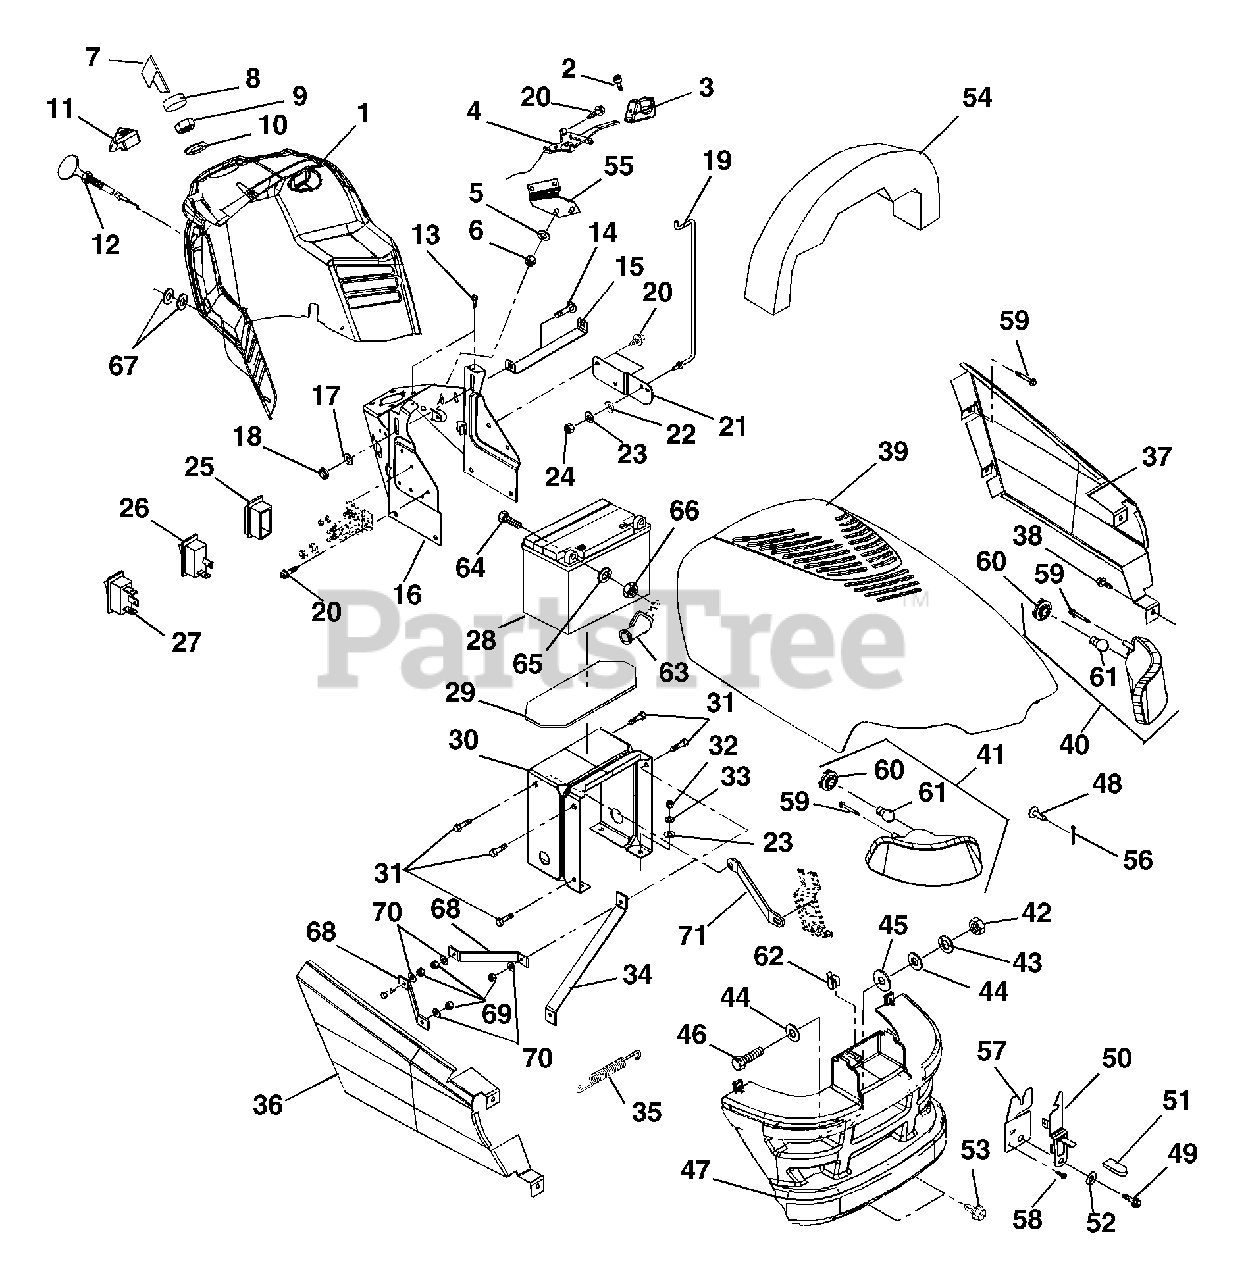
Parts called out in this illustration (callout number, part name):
1	DASH-VENTED
2	SCR-SET 10-24X.38 UNC-3A
3	KNOB, THROTTLE
4	THROTTLE CONTROL- TEC/B&S
5	WSHR-FL-STL .323X.625X.062 YWZ
6	@NUT-LK-CTR .25-20 YWZC
7	IGNITION SWITCH KEY
8	CAP - IGNITION SWITCH
9	NUT- PANEL .562-24 GRECO
10	WSHR-LK-INT .625X.045 YWZC
11	PTO SWITCH ASSEMBLY
12	CHOKE CABLE
13	SCR-TAP 10-24X.484 HWH TR
14	@BLT-RDHDSQNK .31-18X.75 G5YZ
15	HOLDDOWN - BATTERY
16	SUPPORT - DASH - TOP
17	WSHR-FL-STL .323X.625X.062 YWZ
18	@NUT-LK-NYL .312-18 YWZC
19	ROD - HOOD PROP
20	@SCR-TAP .25-20X.37 HWH YWZ TR
21	MOUNT - PROP ROD
22	WAVE WASHER .390X.655X.110
23	@WSHR-FL-STL.312X.734X.065 YWZ
24	@NUT-LK-CTR .25-20 YWZC
25	COVER - SWITCH
26	SWITCH - LIGHT
27	SWITCH - CRUISE
28	BATTERY, 300 CCA 10U1L
29	RUBBER PAD
30	SUPPORT DASH BASE
31	@SCR-TAP .31-18X.50 HWH TR YWZ
32	@NUT-HEX .31-18 YWZC
33	WSHR-LK .312X.097 HVY YWZC
35	SG-TENS .035X.45X2.75 WLD 3.5
36	PANEL, R.H
37	PANEL, L.H
38	SCR-TAP 12-16X.500 HI-LOTPHBL
39	HOOD, ARIENS W/SLOTS
39	HOOD - ARIENS
40	HEADLIGHT- LH
41	HEADLIGHT- RH
42	@NUT-HEX .31-18 YWZC
43	WSHR-LK .312X.097 HVY YWZC
44	WSHR-FL-STL .328X1.0X.094 YWZC
45	WSHR-FL-NYL .390X1.000X.062
46	@BLT-HEX .31-18X1.00 GR5 YWZC
48	PIN, CLEVIS .243/.248X1.50 YWZ
49	SCR-TAP 12-24X.50 HWH TR BLACK
50	HOOD LATCH
51	GRIP .062 X .375 X 1.000 RE
52	WSHR-FL-STL .281X1.250X.048 BL
53	SCR-TAP .312-18X.50 HWH TR BL
54	BAFFLE, FOAM (INTEK V TWIN)
54	BAFFLE- HOOD
55	BRACE-THROTTLE CONTROL
56	@PIN-CTR .09X.75 EXTPRSQCT YWZ
57	LOCATOR- HOOD
58	SCR-TAP 10-12X.50 CRPH PL A BL
59	SCR-TAP 10-24X.75 HWH TR YWZC
60	LAMP SOCKET
61	HEADLIGHT BULB, 1156
62	CLIP-HARNESS TINNERMAN
63	INSULATOR
64	@BLT-HEX .25-20X.75 GR5 YWZC
65	WSHR-LK .250X.077 HVY YWZC
66	@NUT-HEX .25-20 YWZC
67	WSHR-FL-STL .219X.500X.049BLZC
68	BRACKET-STEERING ASSEMBLY
69	@NUT-LK-NYL .312-18 YWZC
70	@WSHR-FL-STL.344X.688X.065YWZC
71	BRACKET-STEERING ASSEMBLY
